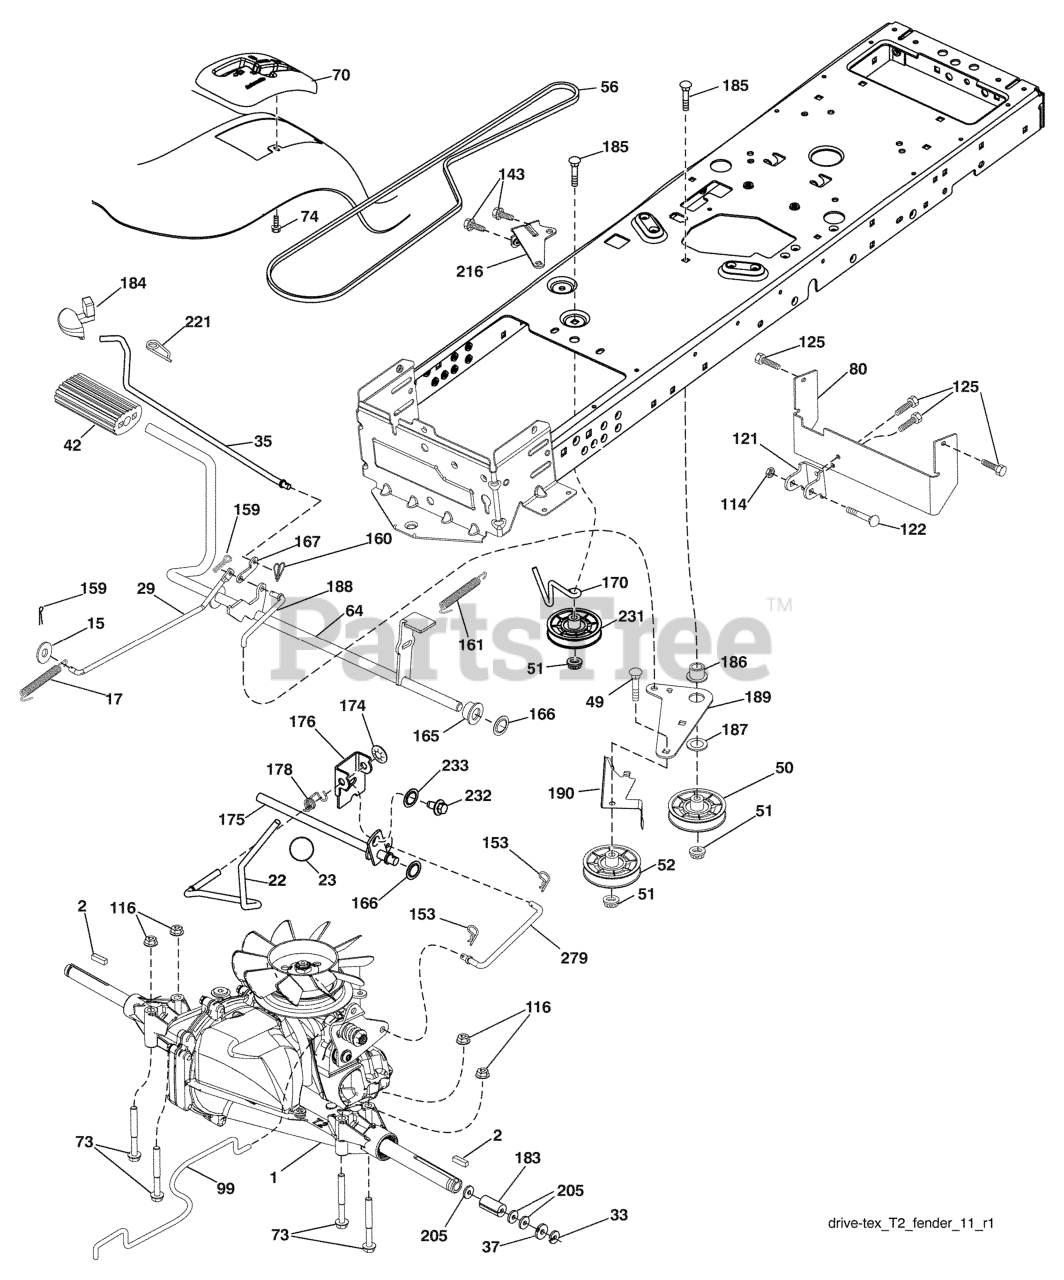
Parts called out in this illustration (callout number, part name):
2	SQUARE KEY
15	WASHER
17	SPRING.BRAKE.HG3000/3500
22	ROD.SHIFT.FENDER.TLT.2006
23	KNOB.DELUXE.(PISTOL.GRIP).BLAC
29	ROD.BRAKE.T2.TEX
35	ROD.CNTRL.PARK.PREDATOR.LT.TEX
42	PEDAL COVER T
50	IDLER.FLAT.910.OFFSET
51	NUT LOCK FLG 3/8-16 UNC
52	IDLER.V-GROOVE.910.OFFSET
64	SHAFT.ASM.PEDAL.BRAKE.
70	CONSOLE SHIFT
73	BOLT HEX 5/16-18 GR 5
74	SCREW.HI-LO.CONSOLE
80	RP.STRAP.TORQUE.FS.T2
99	ROD.ASM.BYPASS.SPRING.T2.FS
114	NUT.71038.31-18.HEX.NYLOCK
116	NUT LOCK HEX FLANGE 5/16-18
121	BRACKET STRAP TORQUE
122	BOLT.5/16-18X2.5
125	SCREW
143	Screw THDROL 5/16-18
153	RETAINER M
159	COTTER PIN
160	RETAINER CLIP
161	SPRING, RETURN LT
165	BUSHING.SHAFT.BRAKE.HAND
166	NUT.PUSH.625.2006
167	LATCH.BRAKE.SPRING
170	KEEPER.CENTER SPAN.1.688
174	NUT.PUSH.500.2006
175	SHAFT.ASM.SHFT.T2.TLT
176	ARM.CLEVIS.ROD.SHIFT
178	SPRING.SHIFT.GT2006
183	SPACER, AXLE PVST
184	HANDLE PARKING BRAKE
186	SPACER.RETAINER
187	WASHER 12/32X2X10GA
188	RP.LINK.CLUTCH.GROUND.DRIVE
189	BELLCRANK.GROUND.DRIVE.TEX.
190	KEEPER.BELLCRANK.DRIVE
216	BRACKET.PULLEY.IDLER.W/TEX
221	RETAINER.SPRING.CLIP.H
231	IDLER.V-GROOVE.1.688.OFFSET
232	BOLT FIN HEX 7/16-14 X 1
233	WASHER SERRATED
279	LINK.SHIFT.T2
